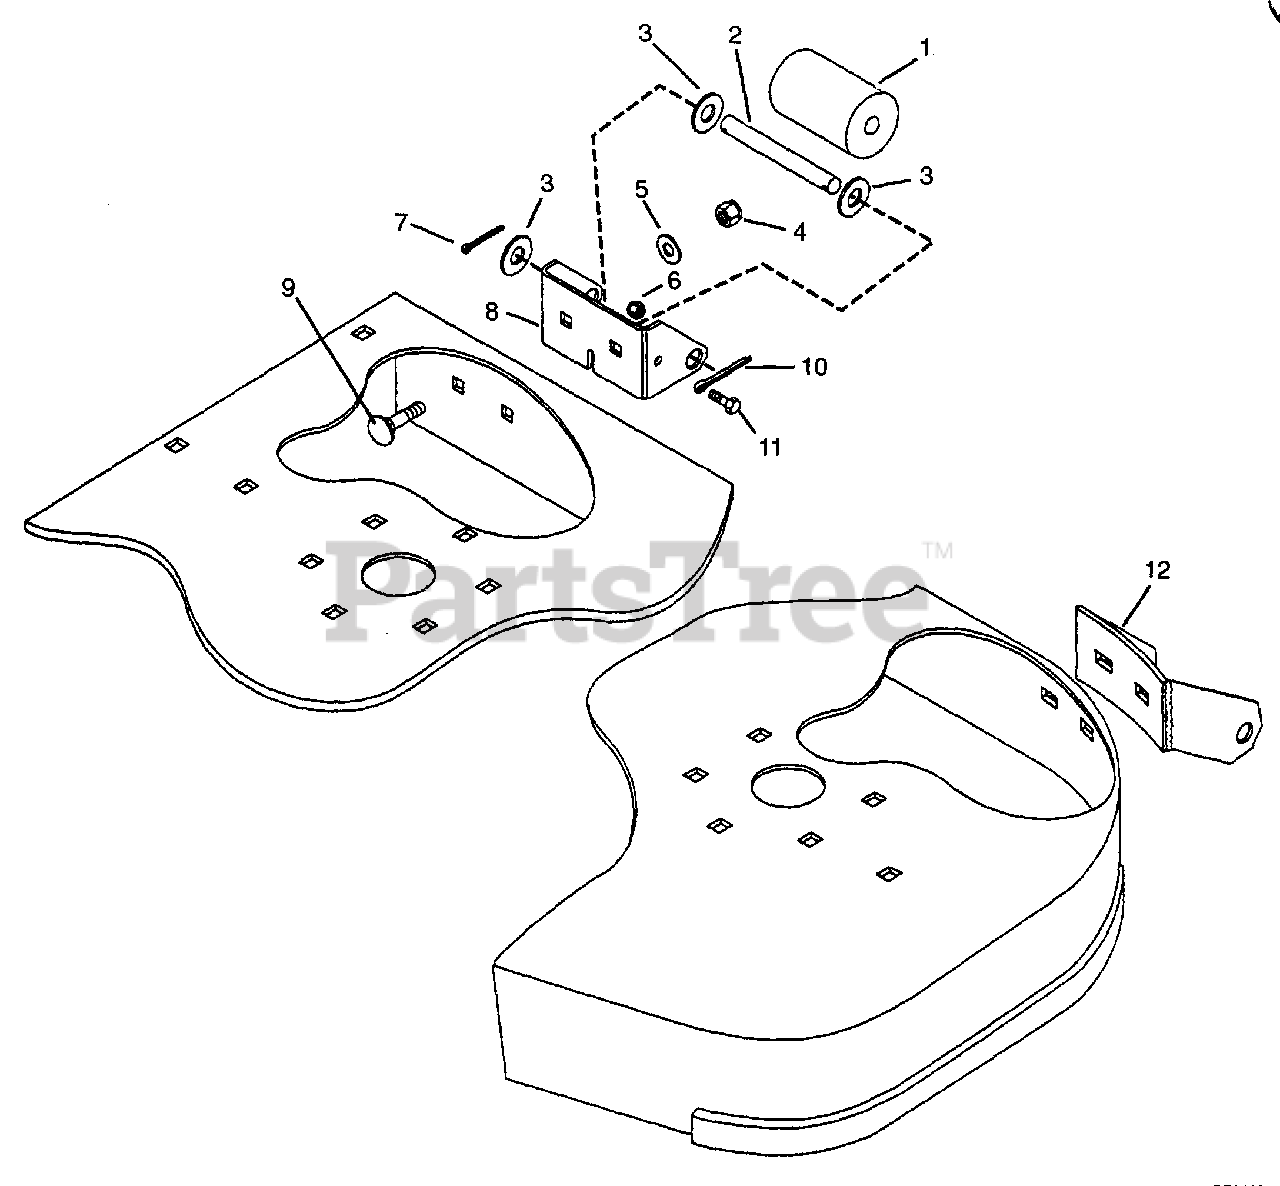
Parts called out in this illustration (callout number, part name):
1	Roller, Gauge
2	Rod
3	Washer-Flat-Steel .656 x 1.31 x .095
4	Nut-Locking-Center .38-16
5	Washer-Flat-Steel .406 x .812 x .065
6	Nut-Locking-Center .25-20
7	Pin-Cotter .25 x 1.00
8	Bracket, Roller
9	Bolt-Round Head Square Neck .38-16 x 1.00
10	Pin-Cotter .250 x 2.00
11	Bolt-Hex .25-20 x .75 Grade 5
12	Weldment, Roller Bracket
